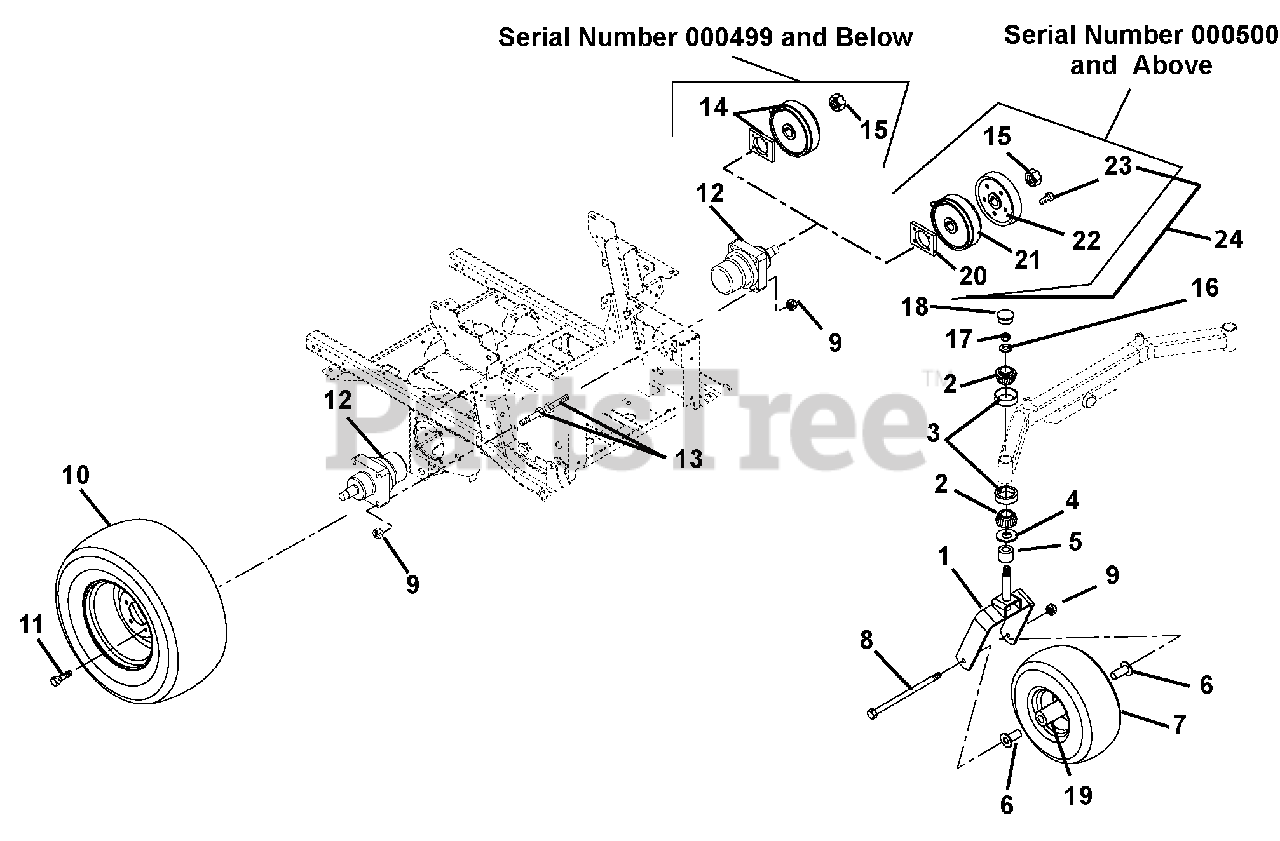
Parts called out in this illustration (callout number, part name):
1	Fork, Front
2	Bearing, Cone w/ Grease
3	Bearing, Cup 1.980 x .420
4	Bearing Seal 1.5 x 2 x .18
5	Spacer, PM, 1.03 I.D. x 1.5 O.D. x .375
6	Spacer, Wheel
7	Wheel/Tire Assembly
7	Tire, 15 x 6-6
8	Bolt, Hex .50-13 x 9.00 Grade 5
9	Nut-Locking-Top-Flange .50-13
10	Tire/Wheel Assembly 24 x 12-12
10	Tire, Turfmaster 24 x 12-12
11	Bolt, Lug .50-20 x 1.38 Grade 8, 60 Degree
12	Hydraulic Wheel Motor (992111, 113, 115, 117, 124)
12	Hydraulic Wheel Motor (992127, 128, 129, 130, 131, 132, 133, 134, 135, 139, 145)
13	Bolt, Wheel Motor .50-13 x 2.75
14	Brake, Park Right Hand
14	Brake, Park Left Hand
15	Nut, Lock Jam Patch
16	Washer, Flat Steel, .812X1.50X.135
17	Nut, Jam Center-Lock .75-16
18	Cap, Dust
19	Bearing, 25mm I.D. x 52mm OD x 15mm
20	Spacer, Brake
21	Kit, Brake Shoe Spare Parts
22	Brake, Hub
23	Bolt, Hex .31-18 x 1.5 Grade 5
24	Kit, Brake Service
